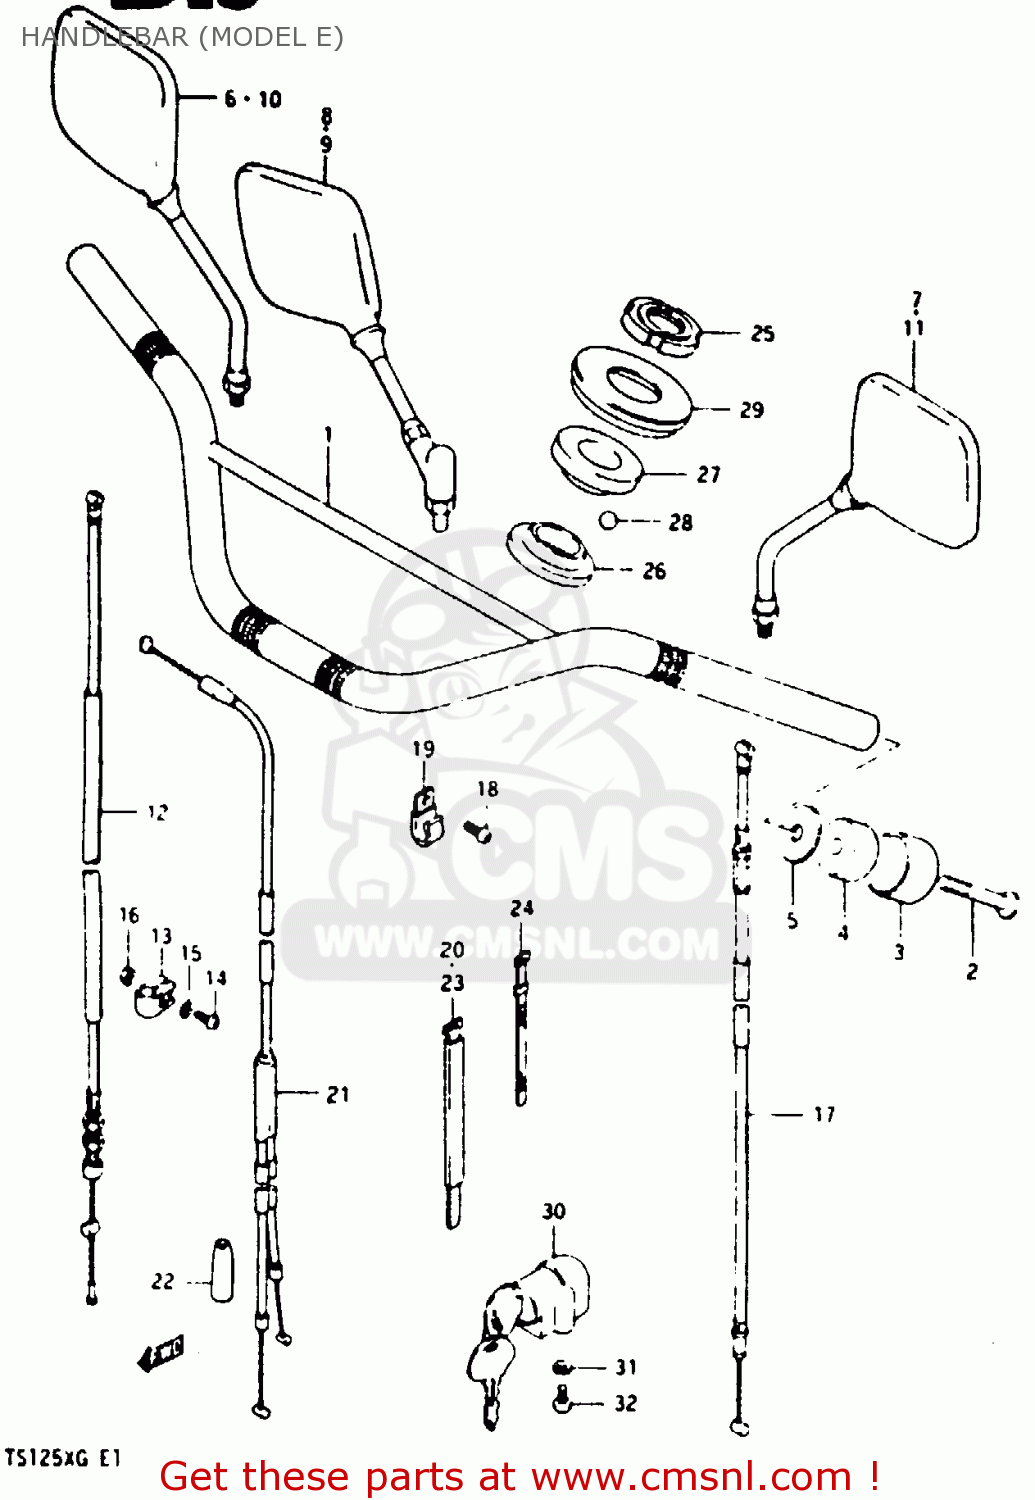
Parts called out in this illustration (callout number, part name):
1	HANDLEBAR (GOLD)
2	SCREW
3	CAP,HANDLE BALANCER
4	BALANCER,HANDLEBAR
5	SPACER,BALANCER
8	MIRROR ASSEMBLY,REAR VIEW
9	MIRROR ASSEMBLY,REAR VIEW
12	CABLE,FR BRAKE
13	CLAMP,FR BRAKE CABLE
14	SCREW 5X20
15	LOCK WASHER
16	NUT
17	CABLE, CLUTCH
18	SCREW
19	CLAMP
20	CLAMP(L:250)
21	CABLE ASSY, THROTTLE
22	SEAL,DUST(7X18X30)
23	CLAMP(L:120)
24	CLAMP
25	NUT,STEERING STEM
26	RACE,STEERING,INNER,UPPER
27	RACE,STEERING,OUTER,UPPER
28	BALL
29	SEAL,STEERING UPR DUST
30	LOCK ASSY,STEERING
31	LOCK WASHER
32	SCREW
